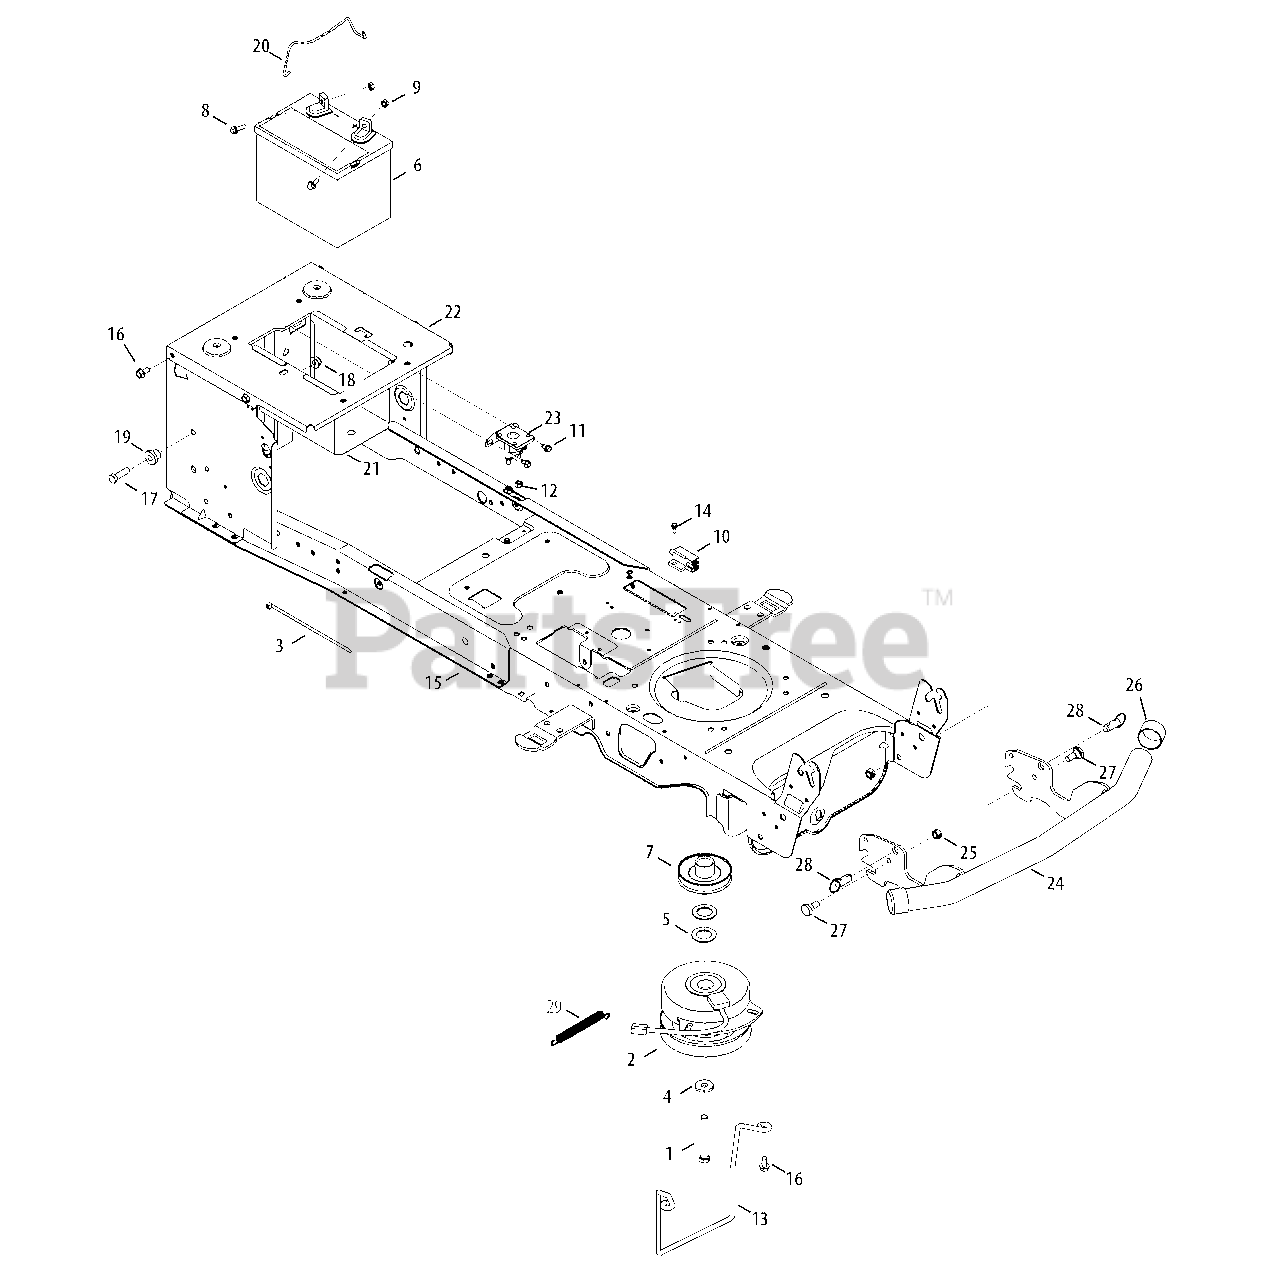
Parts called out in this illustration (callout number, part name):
1	Hex Screw, 7/16-20, 3.50, Gr5, Lock
2	Clutch, Electric PTO, 54"
2	Clutch Harness Wire 11.625"
3	Cable, Tie, 3/16 X .05 X 7.4
4	Washer, Flat, .450 x 1.25 x .164
5	Washer, Flat, 1.031 X1.620 X.095
7	Engine Pulley, Electric PTO
8	Hex Flange Screw, 1/4-20, .75, Gr5
9	Nut, Sems, 1/4-20
10	Switch, Interlock
11	Screw, Self-tapping, 1/4-20, 0.375
12	Nut, Flange Lock, 1/4-20, Nylon
13	Rod, Keeper
14	Screw, Shoulder, #10-32, .50
15	Frame Assembly, Lower
16	Screw, Self-tapping, 5/16-18, .750
17	Hex Screw, 3/8-16, 1.25, Gr5
18	Nut, Flange Lock, 3/8-16, Nylon
19	Spacer, Shoulder, .38 X 1.0 X .70
20	Rod, Battery
21	Tray, Battery
22	Bracket, Frame, Seat
23	Solenoid, 12V, 100 Amp, 4 term
24	Bumper Assembly, Universal
25	Hex Lock Nut, 3/8-16
26	Cap, Bumper
27	Bolt, Shoulder, .496 x .336, 3/8-16
28	Pin, Quick Release, 1/2 Dia x .50
29	Spring, Extension, .56 Dia X 5.52
